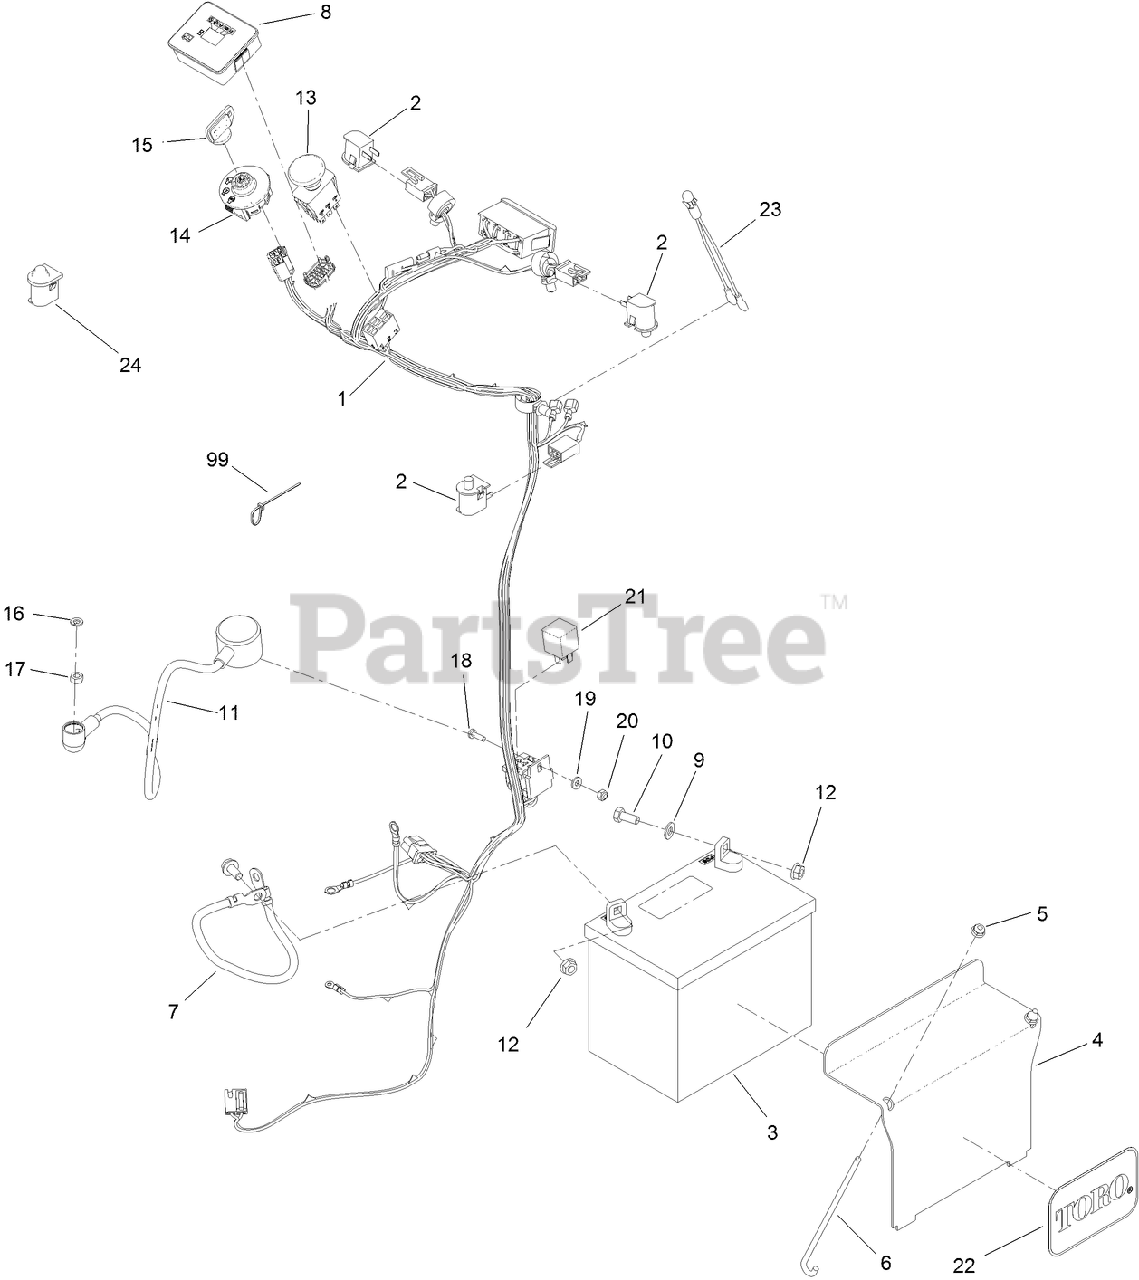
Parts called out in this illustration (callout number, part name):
1	HARNESS-WIRE
2	SWITCH-BAIL
3	BATTERY-DRY
4	BRACKET-HOLD DOWN, BATTERY
5	NUT-HF
6	BOLT-HOLDDOWN
7	CABLE-BATTERY, BLACK
8	MODULE-METER, HOUR
9	WASHER-PLAIN
10	SCREW-HH
11	CABLE-BATTERY, POSITIVE
12	NUT-HHF, SMOOTH
13	SWITCH-PTO, ON-ON
15	KEY-IGNITION
16	SCREW-HH
17	NUT-HEX
18	SCREW-PPH
19	WASHER-FLAT
20	NUT-LOCK, NI
22	DECAL
23	INDICATOR-LED, RED
24	SWITCH-PLUNGER
99	TIE-CABLE
